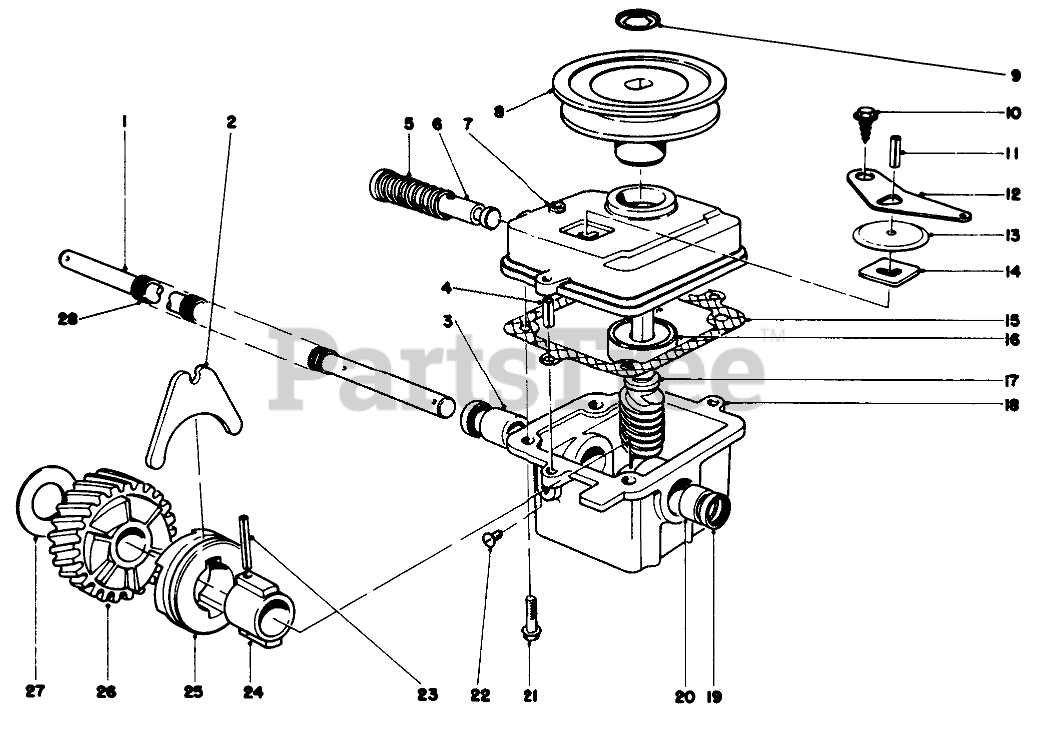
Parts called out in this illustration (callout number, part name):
1	DRIVE SHAFT (SERVCE)
2	SHIFTER FORK
3	Bushing
4	3/16 X 1/2 ROLL PIN
5	SPRING
6	Shift Rod
7	Cover Gear Case
8	PULLEY
9	PUSH-ON 93-3236
10	Screw
11	PIN-ROLL
12	SHIFTER ARM
13	TRANS DUST COVER
14	LATCH PLATE
15	Gasket-Gear Case
16	Ball Bearing
17	Worm Shaft (Incl. Ref. #26)
18	Gear Case (Incl. Ref. #3, 19-20)
19	Seal
20	Bushing
21	Screw
22	NYLON SCREW
23	Pin
24	SLEEVE
25	CLUTCH JAW
26	Helical Gear
27	THRUST WASHER
28	COVER-SHAFT, DRIVE
